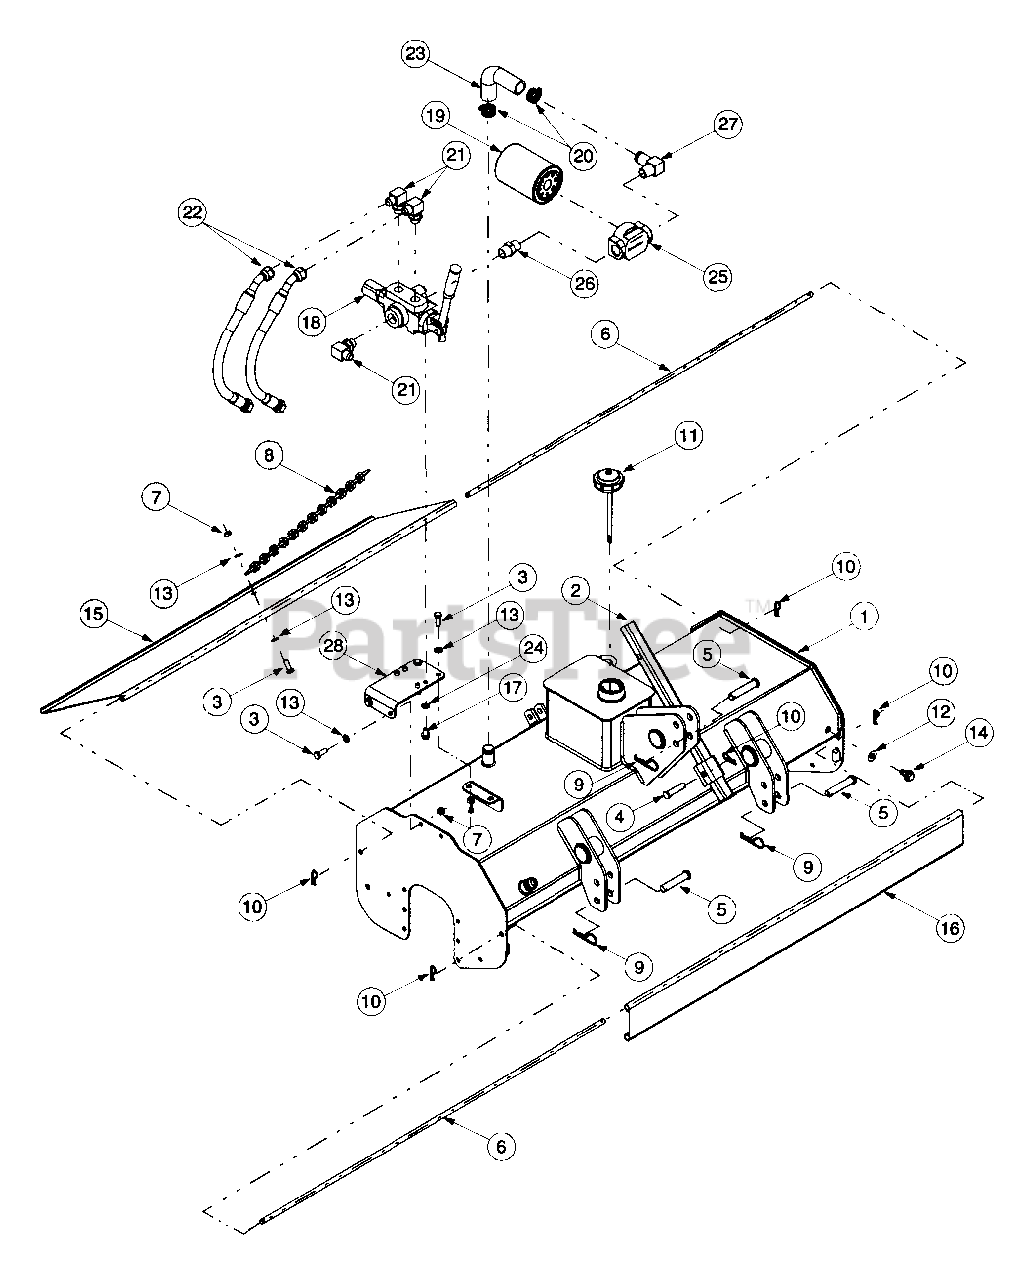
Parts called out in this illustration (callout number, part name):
1	42" Tiller Frame Assembly
3	Hex Cap Screw, 3/8-16 x 1.0
4	Clevis Pin, .50 x 2.0
5	Clevis Pin, 5/8 Dia. x 2 13/16
6	Shield Pivot Rod
7	Hex Lock Nut, 3/18-16, Ctr Lock
8	Shield Chain, 24.37
9	Internal Cotter Pin, .148 x 3
10	Internal Cotter Pin
11	Vented Tank Cap
12	Stat-O-Seal O Ring
13	Flat Washer, .375 x .738 x .063
14	Oil Drain Plug
15	Rear Tine Shield, 42"
16	Front Tine Shield, 42"
17	Hex Washer Hd Screw, 3/8-16 x .625
18	Energy Hydraulic Valve
19	Oil Filter
20	Hose Clamp
21	90° Hydraulic Adapter, 7/8
22	Hydraulic Hose, 7/8-14
23	Hydraulic Hose, 90°, 1.37 OD, 1.0 ID
24	Lock Washer, 3/8
25	Filter Housing
26	Hydraulic Adapter, 3/4
27	90° Hydraulic Adapter, 3/4NPTF,1.0
28	Hydraulic Valve Mounting Bracket
